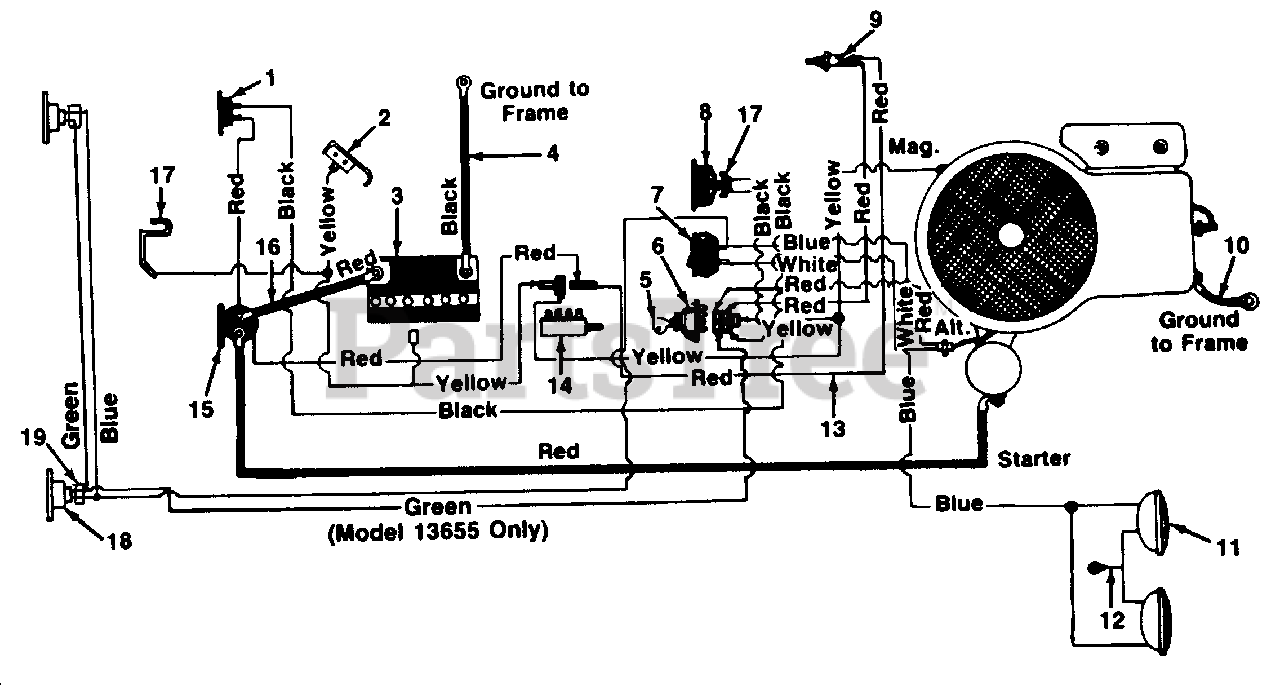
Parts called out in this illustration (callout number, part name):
1	Circuit Breaker
2	Spring Switch
3	1 2V-Battery
4	Grounding Wire 11.5" Lg.
5	Ignition Key
6	Ignition Switch
7	Headlight Switch
8	Ammeter
9	Safety Switch
10	Ground Wire 7.25" Lg.
11	Headlight
12	Ground Wire
13	Wire Harness
14	Safety Switch
15	Solenoid
16	Electric Wire 8.0" Lg.
17	Spring Switch
18	Taillight
19	Mounting Clamp
